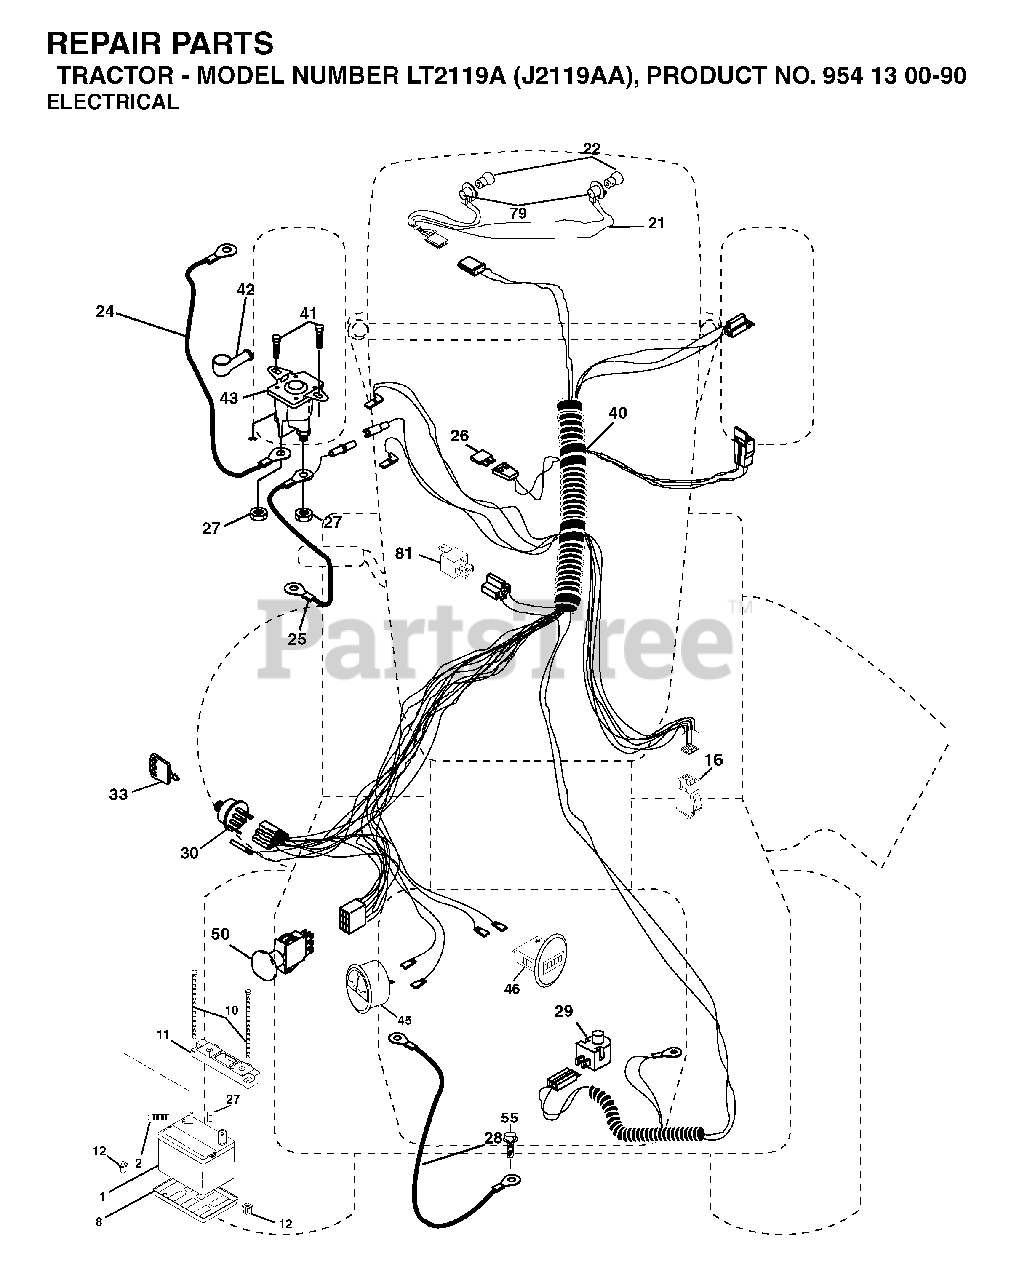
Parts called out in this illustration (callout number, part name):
1	BATTERY 12V .35 AMP
8	BATTERY TRAY T
10	BOLT 1/4-20 X 7.5
11	BATTERY HOLDDOWN
12	NUT, PUSH NYLON 1/4" BATTERY
16	SWITCH INTERLOOK PUSH-IN
21	HARNESS.W/LIGHT SOCKET
22	LIGHTBULB
25	CABLE BATTERY 6 GA 22" W/16W
26	FUSE 20AMP
27	NUT
28	CABLE GROUND 6 GA 21" 90T BLK
29	PLUNGER SWITCH (COLOR:OLIVE)
30	IGNITION SWITCH
33	KEY MLD GEN DELTA
41	SCREW
42	TERMINAL COVER
43	SOLENOID
46	HOURMETER SNAP-IN
50	PTO SWITCH
79	BULB HOLDER ASM.
81	RELAY.ASSY.T
